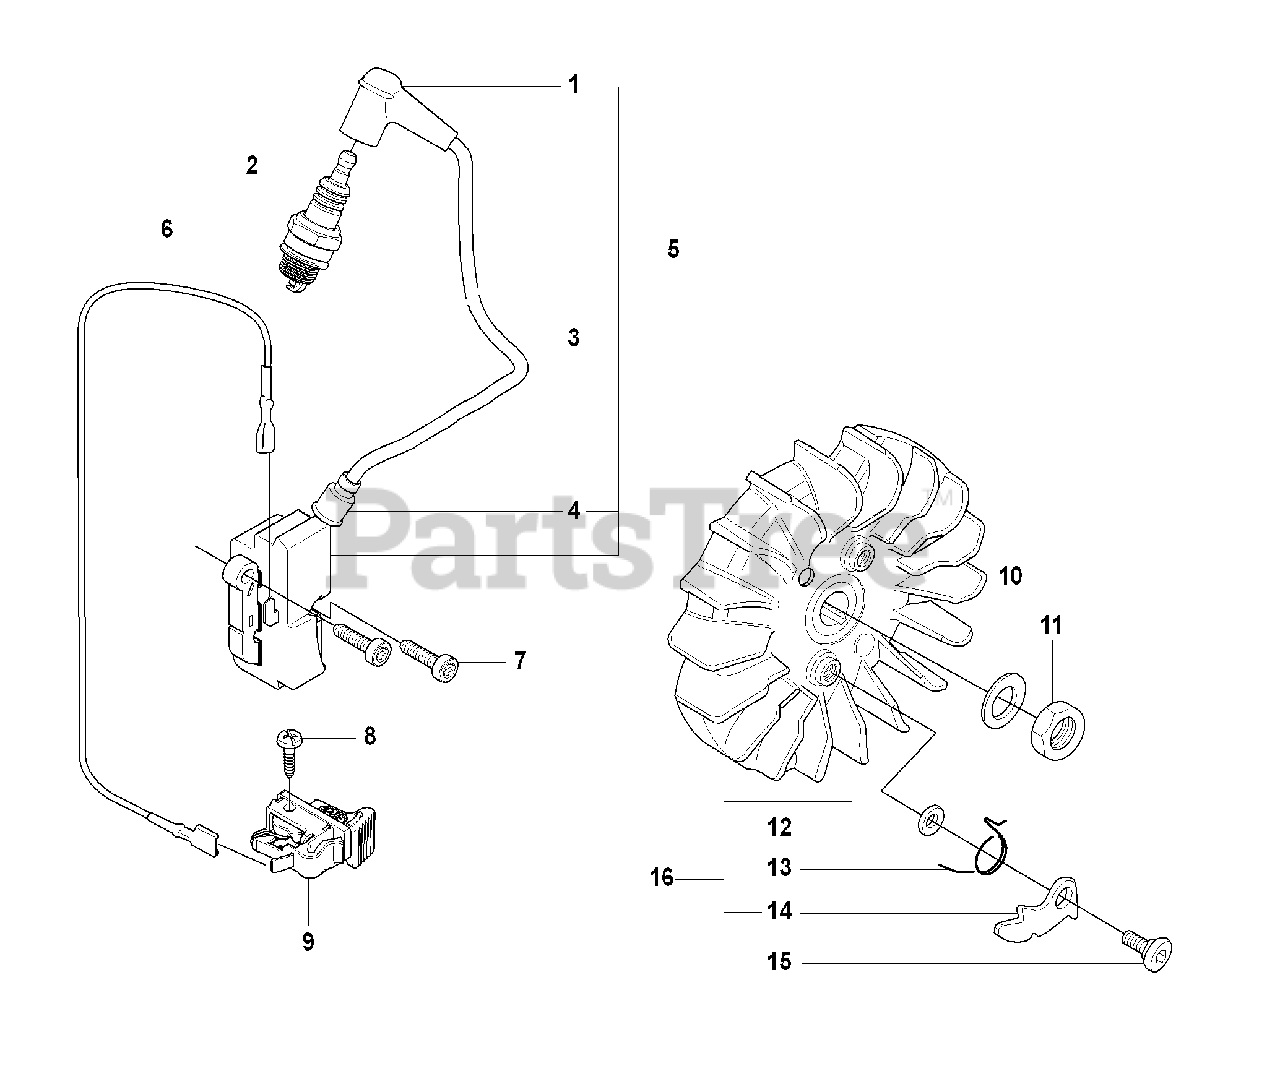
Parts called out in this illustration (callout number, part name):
1	SPARK PLUG CAP
2	SPARK PLUG
3	IGNITION CABLE
4	INSULATING CAP
5	IGNITION MODULE
9	STOP SWITCH
10	WASHER STEEL
12	WASHER STEEL
16	FLYWHEEL
